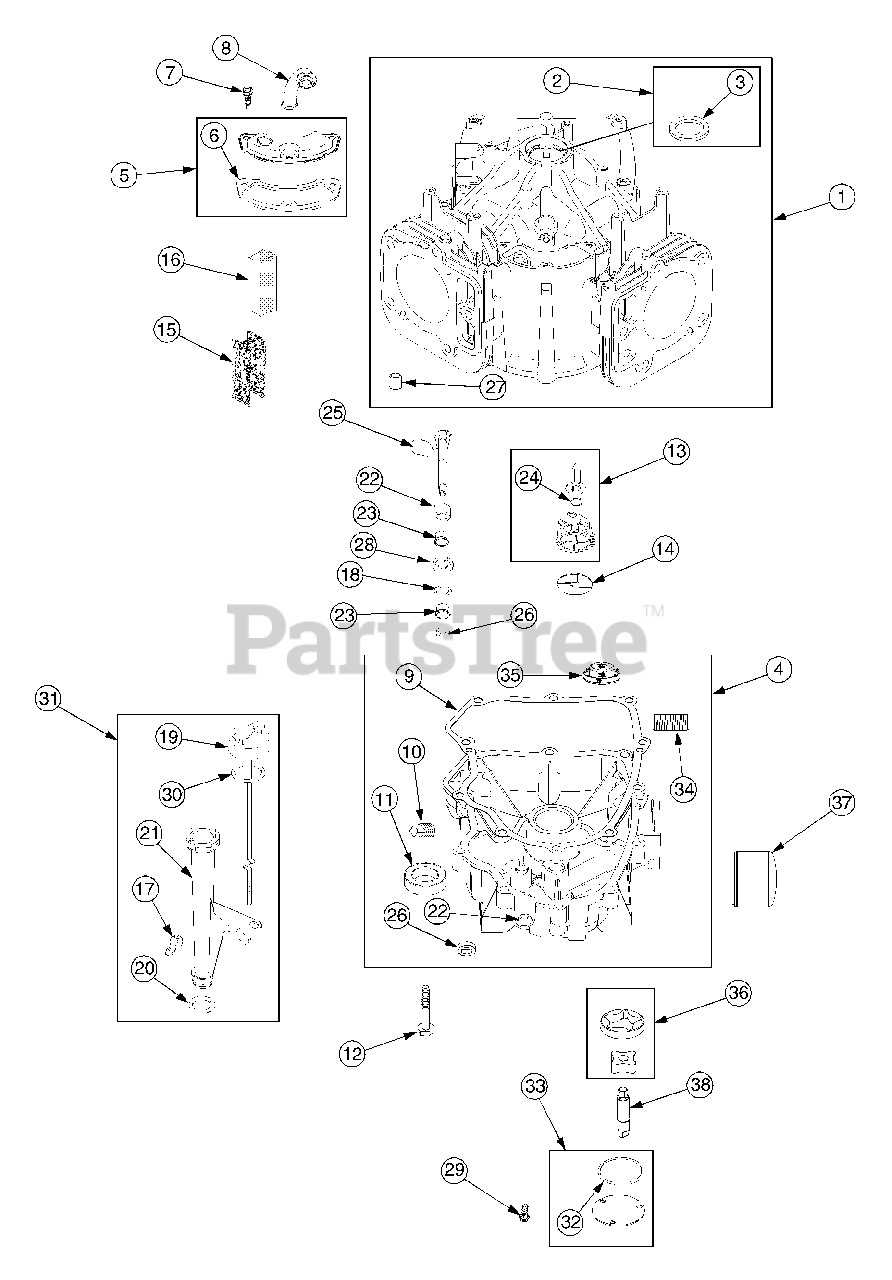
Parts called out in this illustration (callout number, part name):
1	Cylinder Assembly
2	Kit, Bushing/Seat (Magneto Side)
3	Seal, Oil (Magnetor Side)
4	Sump, Engine
5	Breather Assembly
6	Gasket, Breather
7	Screw, Breather Assembly
8	Tube, Breather
9	Gasket, Crankcase
10	Plug, Oil Drain
11	Seal, Oil (PTO Side)
12	Screw, Engine Sump
13	Gear, Governor
14	Washer, Governor Lever
15	Retainer, Breather
16	Collector, Oil
17	Screw, Dipstick Tube
18	Washer, Governor Crank
19	Dipstick
20	Seal, Dipstick Tube
21	Tube, Dipstick
22	Bushing, Governor Crank
23	Bushing, Governor Crank
24	Retainer, Governor Shaft
25	Crank, Governor
26	Seal, Governor Shaft
27	Pin, Locating
28	Retainer, E-ring
29	Screw, Oil Pump Cover
30	Seal, Dipstick Tube
31	Dipstick Tube Assembly
32	Seal, O-ring (Oil Pump Cover)
33	Cover, Oil Pump
34	Nipple, Oil Filter
35	Screen, Oil Pump
36	Pump, Oil
37	Filter, Oil
38	Shaft, Pump
